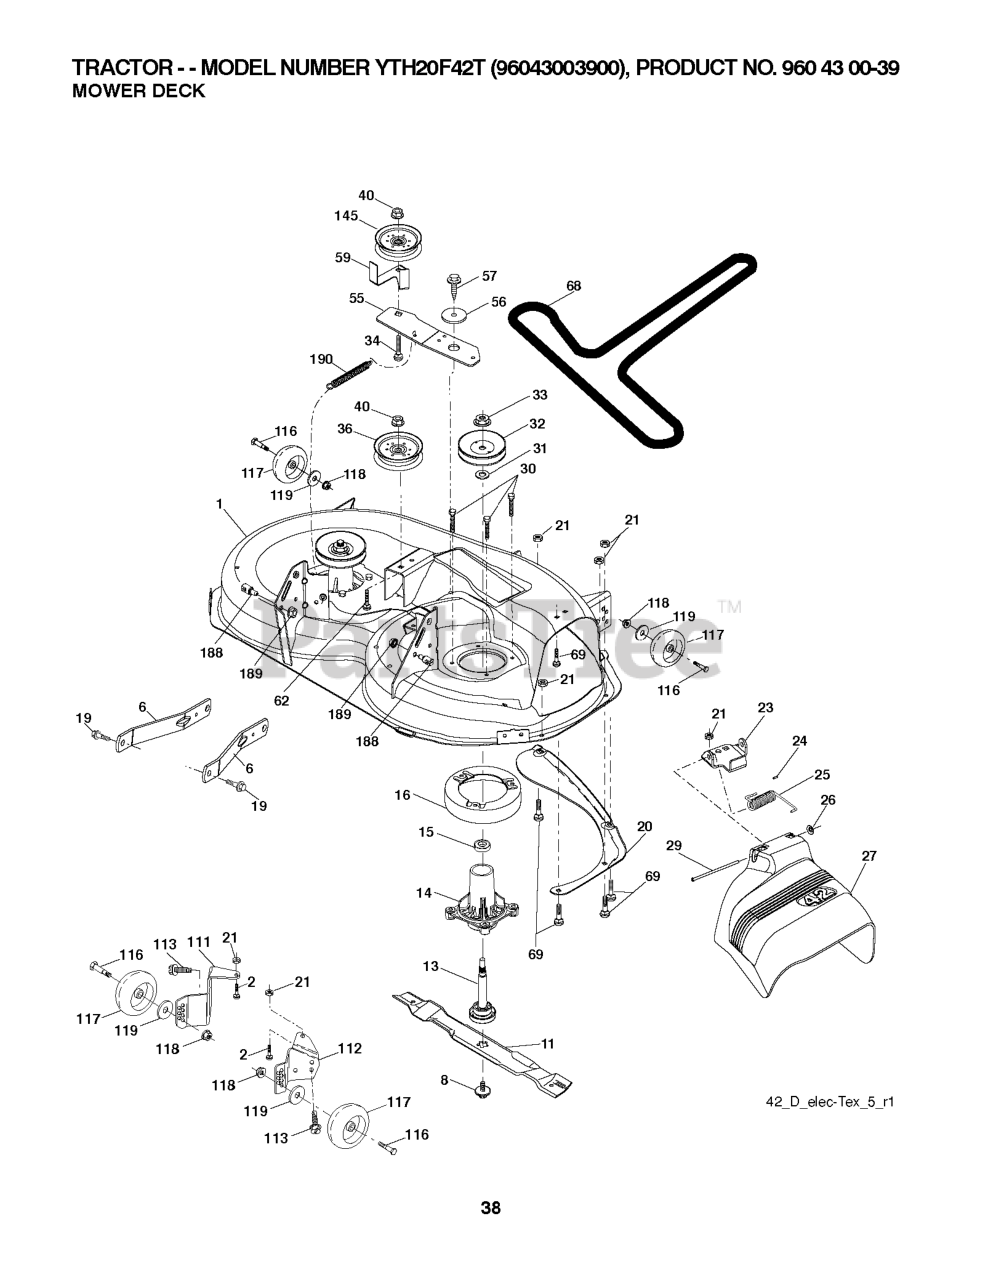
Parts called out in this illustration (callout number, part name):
1	DECK.WELDMENT.42"PAINT
2	RP BOLT 5/16-18 X3/4 ZN/YEL GR
6	ARM.SUSPENSION.MOWER.R
8	BOLT.WASHER.ASM.7/16-2
11	42" HI-LIFT BLADE
13	SHAFT.ASM.MDRL.N/GREASE.38
14	RP.HOUSING.MANDREL.4PT.
16	STRIPPER.MANDREL.ROUND.BLACK
19	BOLT.SHOULDER
20	BAFFLE.VORTEX
21	LOCKNUT
23	BRKT.DEFLECTOR.38"2005+
24	CAP-SLEEVE LT
25	SPRING.TORSION.DEFLECT
26	NUT PUSH M
27	SHIELD.DEFLECTOR.MOWER.42"BLAC
29	ROD.HINGE
30	SCREW, WASHER HEAD
31	WASHER.SPACER.MANDREL
32	PULLEY/MANDREL
33	NUT.FLANGE.LOCK.TOP
34	BOLT.3/8-16X1.50
36	PULLEY.IDLER.2006
40	NUT LOCK FLG 3/8-16 UNC
56	SPACER.RETAINER
57	SCREW 3/8-16X1
59	GUARD, BELT
68	BELT V SECONDARY
69	BOLT
111	BRKT.WHEEL.GAUGE.LH.42"
112	BRKT.WHEEL.GAUGE.RH.42"
113	BOLT.5/16HEX.WHS.HD
116	BOLT M
117	WHEEL.GAGE.HALF.SPOKED
118	LOCKNUT
119	WASHER.5/16.FLAT.STE.STD.
145	PULLEY.IDLER.48"PRIMARY
188	STUD.FASTNER.W/ANTI-ROTATE
189	NUT LOCK HEX FLANGE 5/16-18
190	SPRING.MOWER.DRIVE.ELECTRIC
